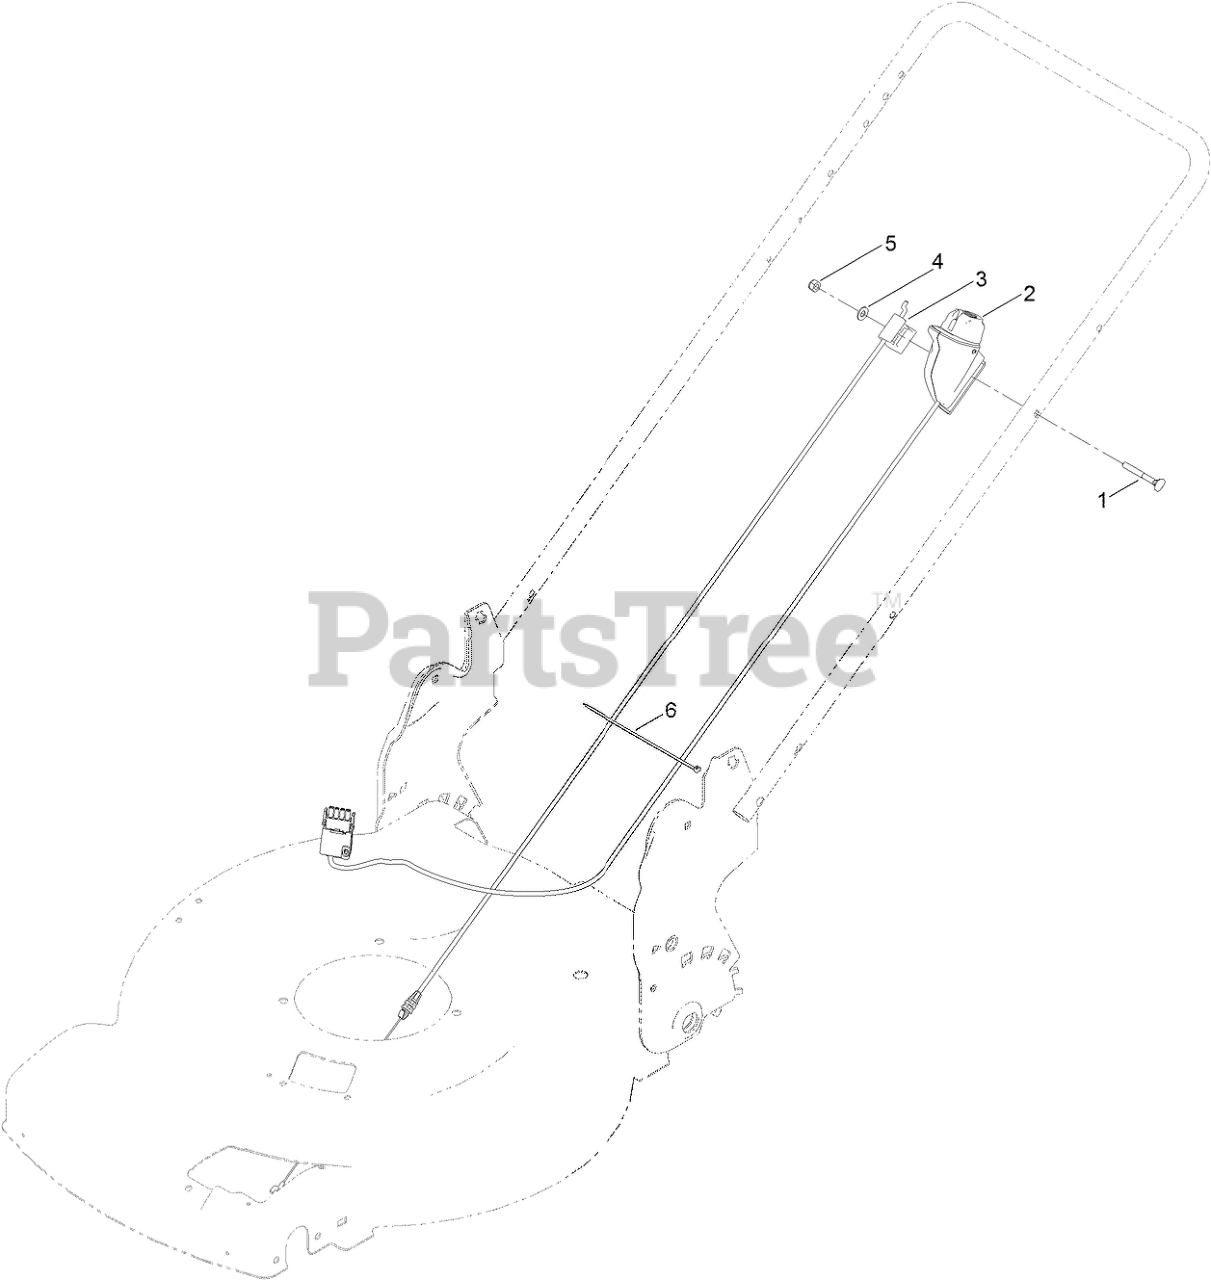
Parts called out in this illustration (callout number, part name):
1	SCREW
2	STARTER SWITCH ASM
3	CABLE-BRAKE, HP
4	WASHER-FLAT
5	NUT-LOCK, NI
6	TIE-CABLE
